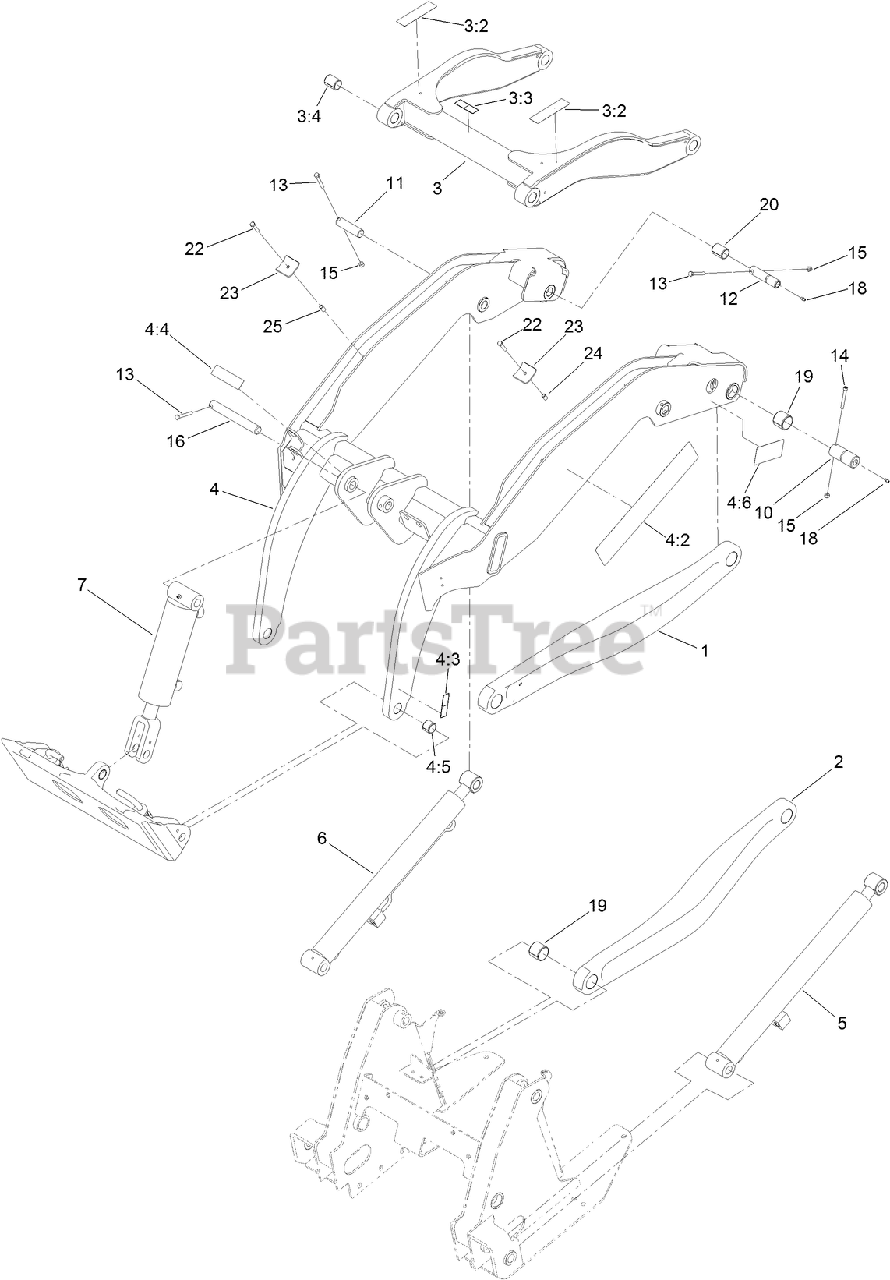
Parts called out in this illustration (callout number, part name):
1	LINK-LOWER, LH
2	LINK-LOWER, RH
3	LINK-UPPER
3:2	DECAL-WARNING, CRUSHING
3:3	DECAL-WARNING, PINCH POINT
3:4	BUSHING-SPRING
4	LOADER ARM ASM
4:2	DECAL-TX1000
4:3	DECAL-WARNING, PINCH POINT
4:4	DECAL-CAUTION
4:5	BUSHING-TENSION
4:6	DECAL-WARNING, PINCH POINT
5	CYLINDER-LIFT, LH
6	CYLINDER-LIFT, RH
7	CYLINDER-HYD, DUMP
10	PIN-ARM
11	PIN-PIVOT
12	PIN-LINK
13	SCREW-HH
14	SCREW-HSH
15	NUT-LOCK, NI
16	PIN-LOCKING
18	FITTING-GREASE
19	BUSHING-SPRING
20	BUSHING-SPRING
22	SCREW-HH
23	PLATE-HOLDDOWN, HOSE
24	SPACER-HOSE
25	SPACER-HOSE
